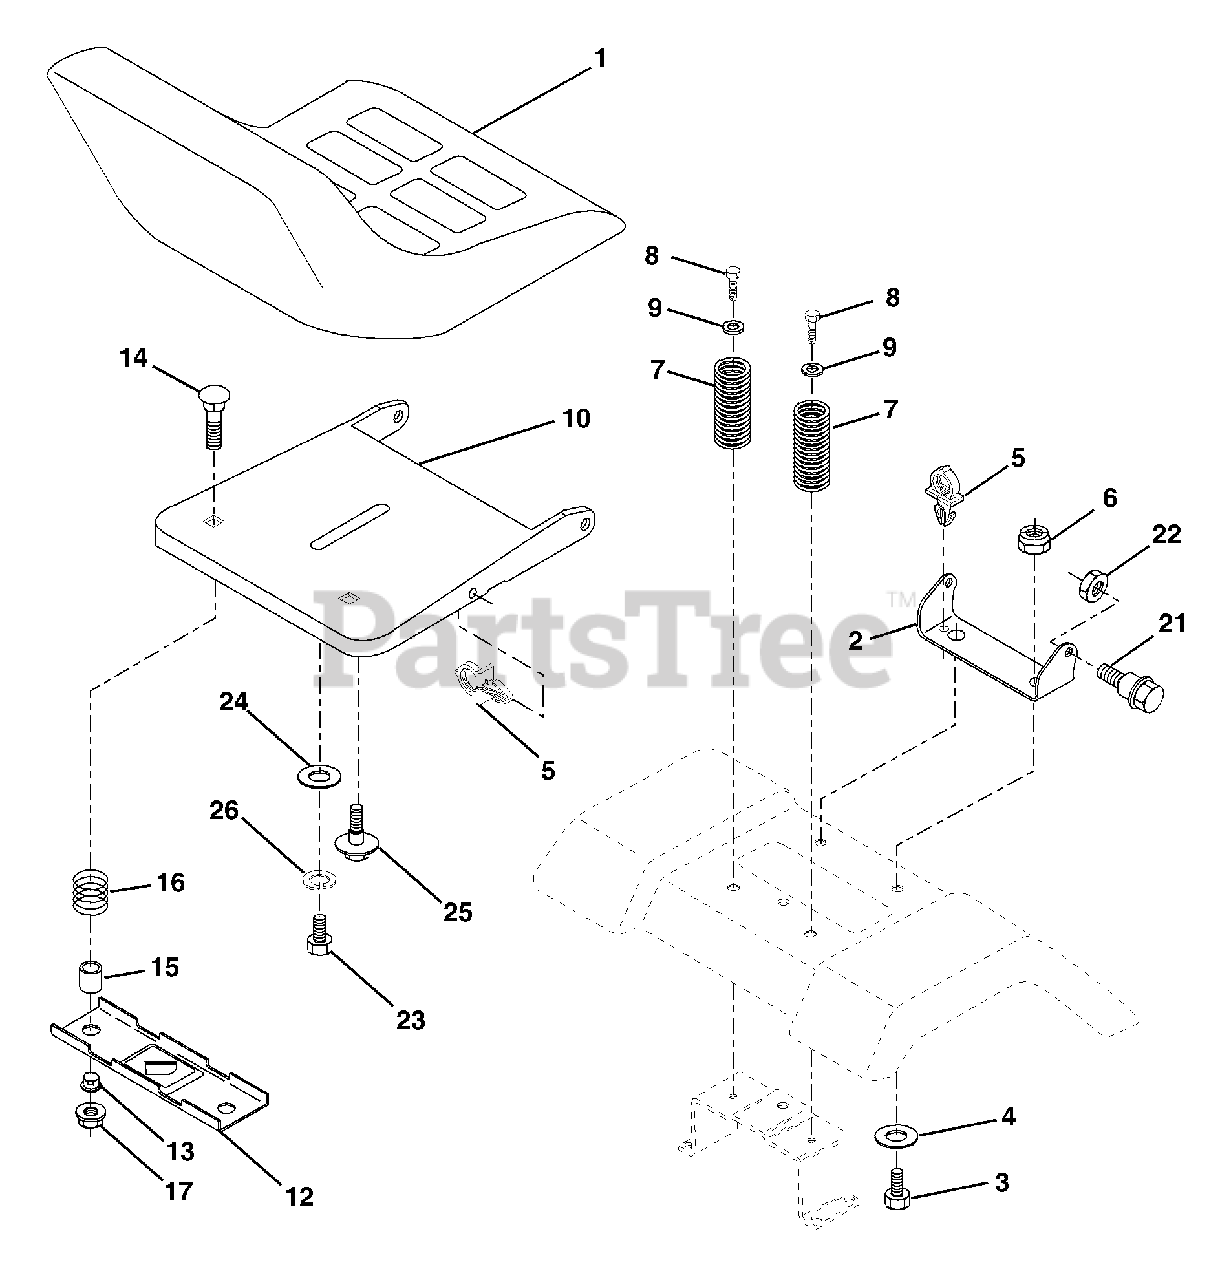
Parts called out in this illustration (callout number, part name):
1	Seat
2	Bracket Seat Pivot
3	Bolt Hex 3/8 - 16 x 1
4	Washer 13/32 x 1 x 10Ga.
5	Clip Push-In Hinged
6	Nut Lock Hex w/Ins 3/8 - 16
7	Spring Seat Cprsn 2 250 Blk Zi
8	Screw 3/8-16 x 1.5
9	Washer 13/32 x 1 x 14 Ga.
10	Pan Pnt Seat (Blk)
12	Bracket Pnt Mounting Switch
13	Bushing Snap Blk Nyl
14	Bolt Rdhd Sht Nk 1/4 - 20 x 1-1/2
15	Spacer Split .28 x .96
16	Spring Cprsn
17	Nut Lock 1/4 Lge Flg
21	Bolt Shoulder 5/16-18 unc-2A
22	Nut Lock Hex w/Ins 5/16 - 18
23	Bolt Hex
24	Washer 17/32 x 1-3/16 x 12 Ga.
25	Bolt Shoulder 5/16-18 x .62
26	Washer Lock Hvy Hlcl Spr 1/2
